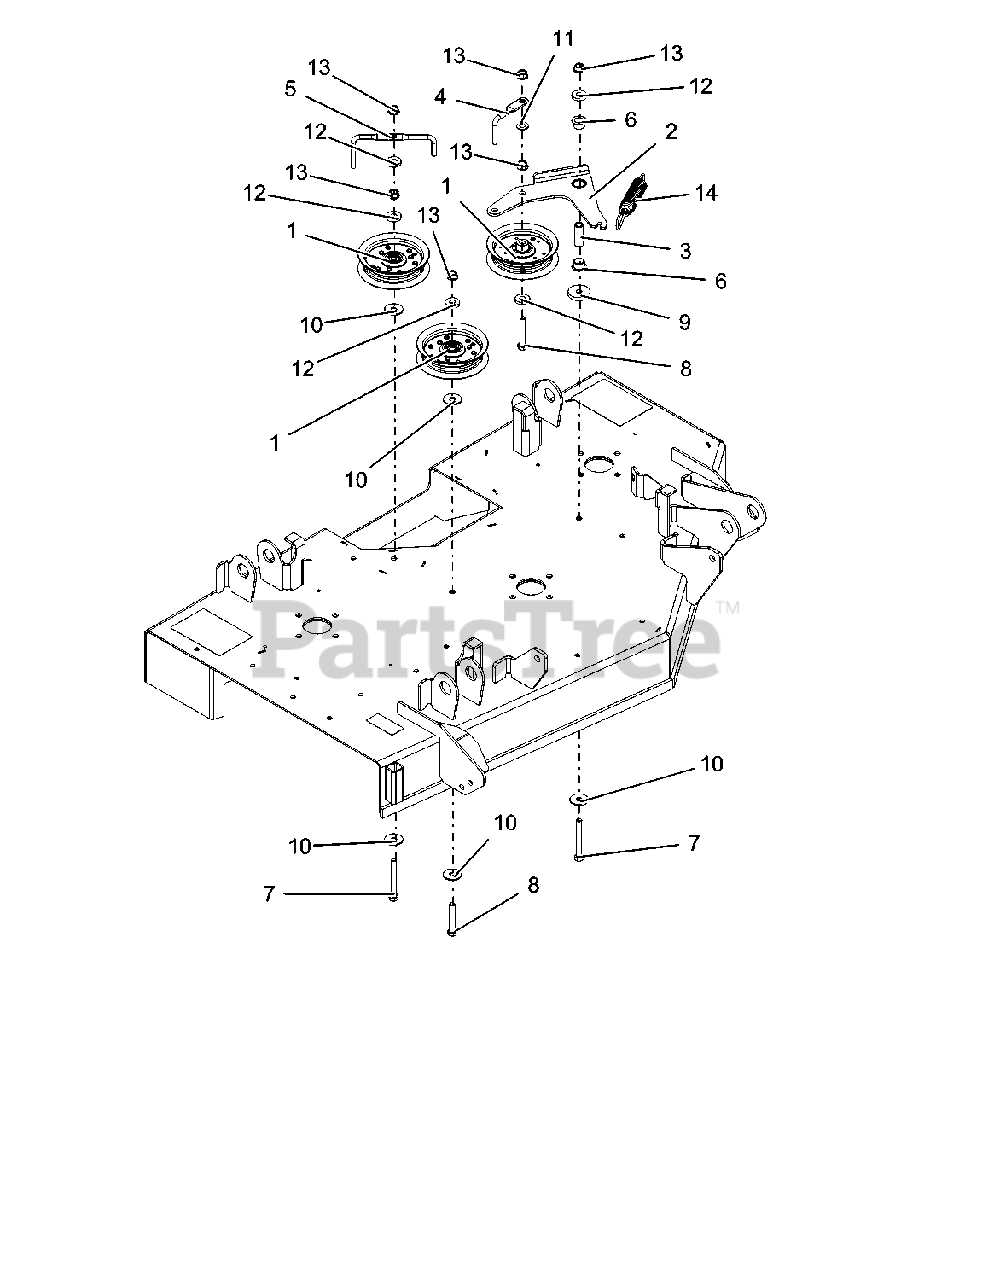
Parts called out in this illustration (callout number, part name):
1	ASM, IDLER 4"
2	WLDMT, IDLER ARM (RED)
3	SPCR, .375IDX.625ODX1.66 PM
4	WIREFORM, BELT FINGER (RED)
5	FINGER, BELT (RED)
6	BSHG, FLANGE .625 x .75 x .50 x 1.00
7	BLT-HEX .38-16X3.00 GR5 FTH YWZC
8	BLT-HEX .38-16X2.25 GR5 YWZC
9	WSHR-FL-STL .406X1.50X.245 YWZC
10	WSHR-FL-STL .406X1.25X.10 YWZC
11	WSHR-FL-STL.406X.812X.065 YWZ
12	WSHR-FL-STL .406X1.00X.188 YWZC
13	NUT, LK-TOP-FLG .38-16 YWZC
14	SPRG, EXTENSION
